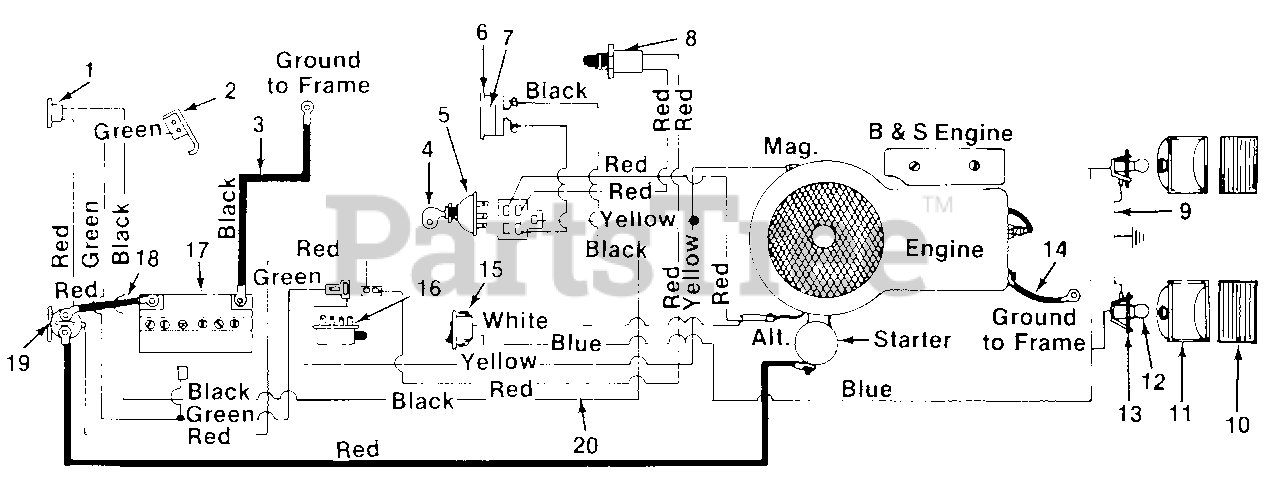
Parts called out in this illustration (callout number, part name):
1	Circuit Breaker
2	Spring Switch
3	Ground Wire 9.0" Lg.
4	Ignition Key
5	Ignition Switch
6	Ammeter
7	Foam Strip
8	Safety Switch
9	Ground Wire
10	Lens
11	Headlight Housing
12	Lamp
13	Socket
14	Ground Wire 7.25" Lg.
15	Light Switch
16	Safety Switch
17	Battery
18	Electric Wi re w/Bolt
19	Solenoid
20	Wire Harness
